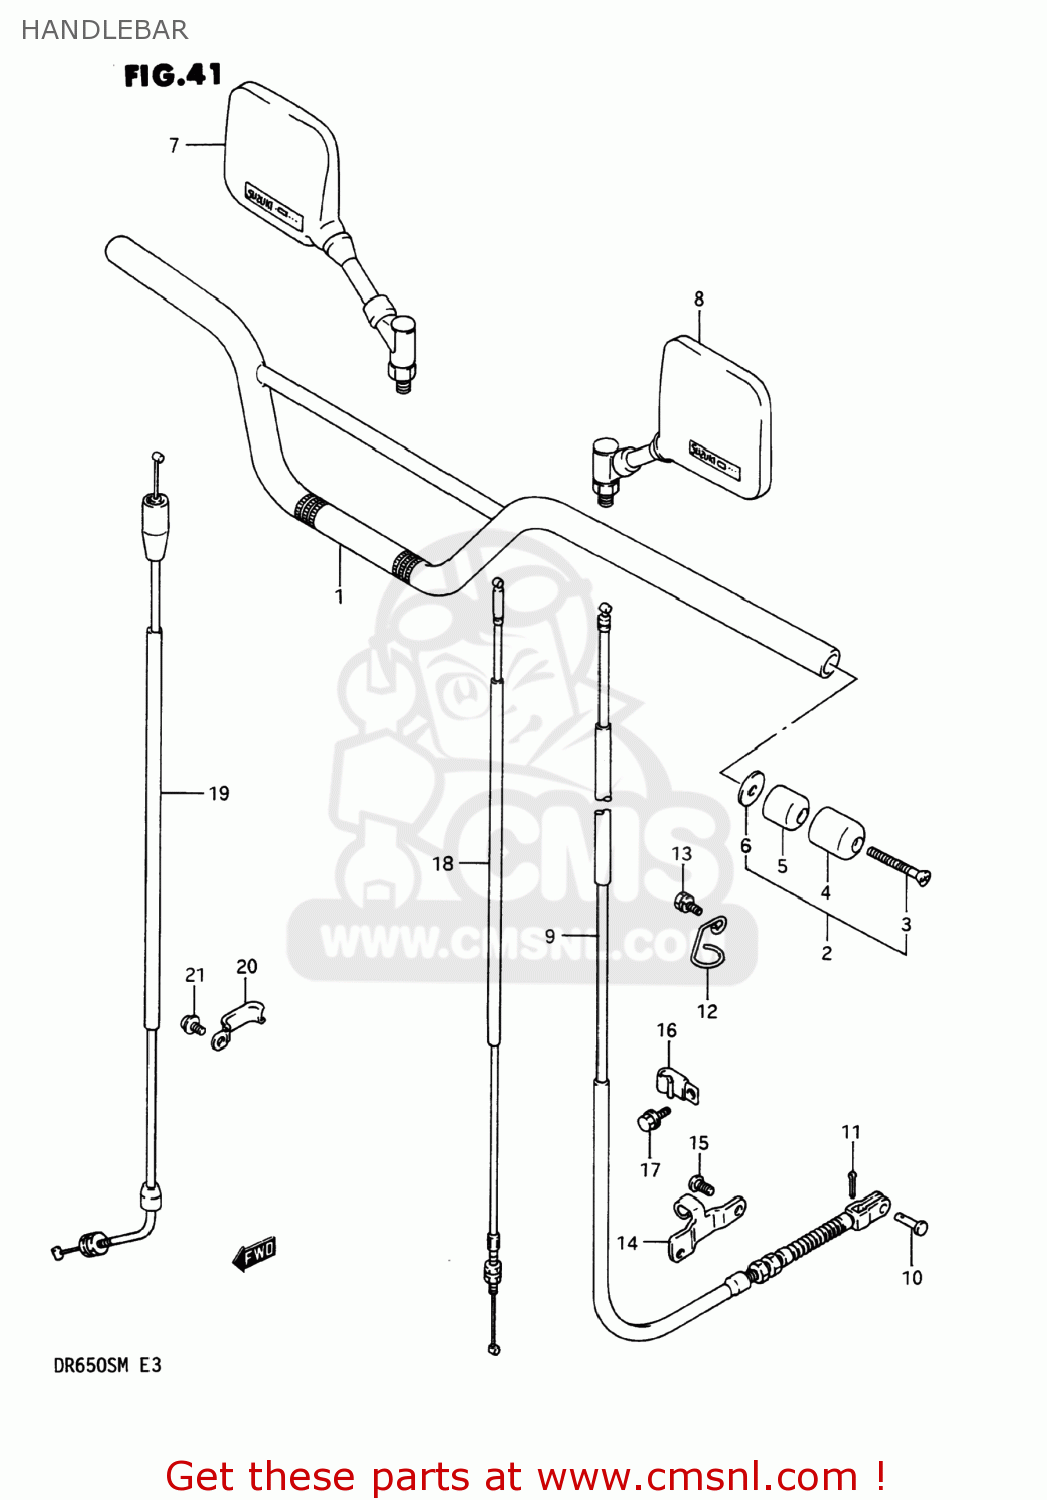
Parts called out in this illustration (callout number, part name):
1	HANDLEBAR COMP
2	BALANCER SET,HANDLEBAR
3	SCREW
4	CAP,BALANCER
5	BALANCER,HANDLEBAR
6	SPACER,BALANCER
7	MIRROR ASSEMBLY,REAR VIEW
8	MIRROR ASSEMBLY,REAR VIEW
9	CABLE ASSY,CLUTCH
10	PIN(L:13)
11	PIN
12	GUIDE
13	BOLT ,6X12
14	STOPPER,CLUTCH CABLE
15	SCREW
16	CLAMP
17	BOLT
18	CABLE ASSY,DECOMP
19	CABLE ASSY,THROTTLE
20	CLAMP
21	SCREW
